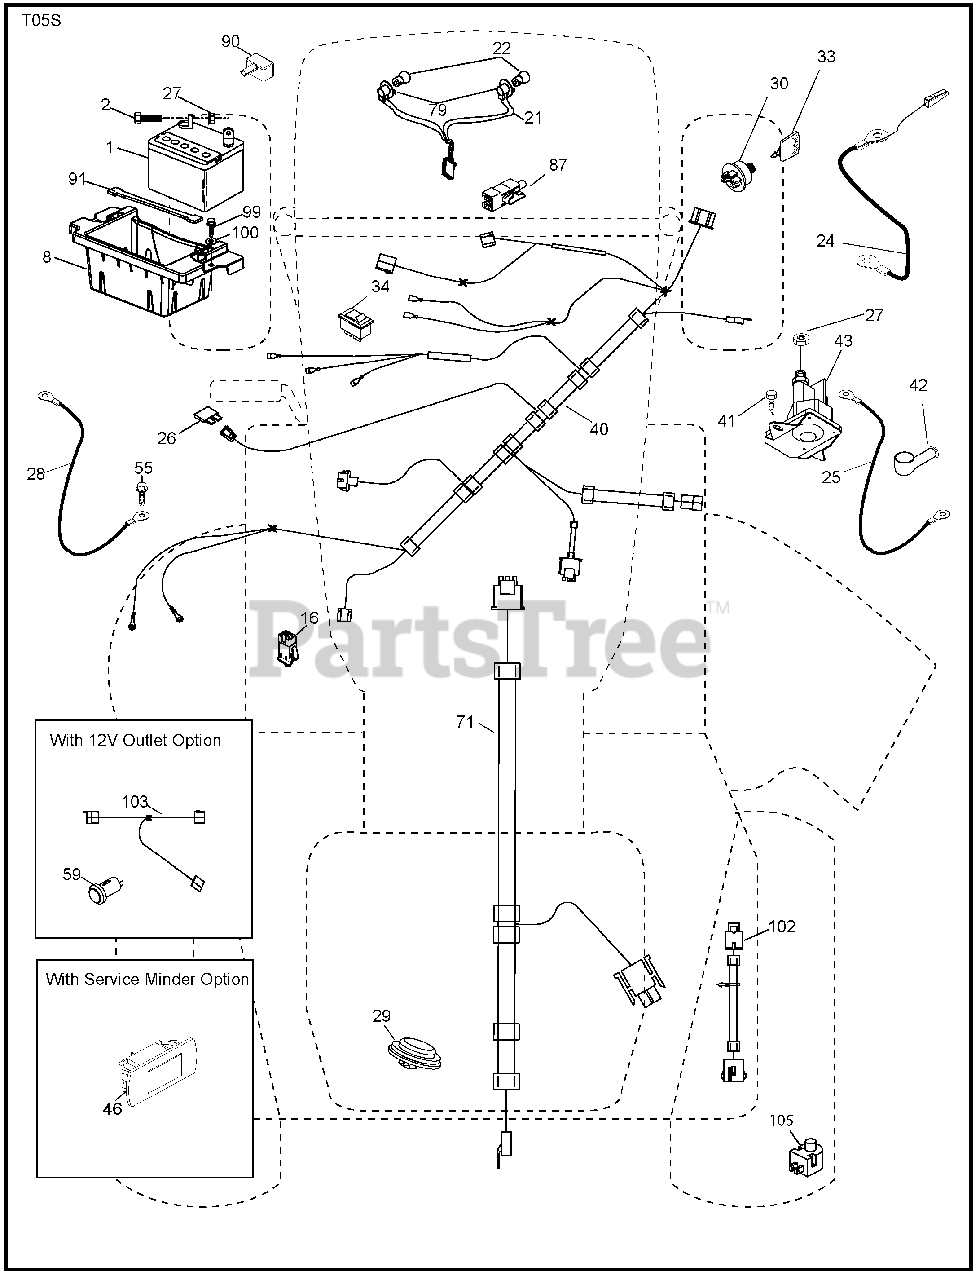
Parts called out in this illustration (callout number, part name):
1	Battery
2	Bolt Hex Head 1/4-20 x 3/4
8	Box Battery
16	Switch Interlock Push-In
21	Harness Socket Light w/4152J
22	Bulb Light
24	Cable Battery
25	Cable Starter
26	Fuse
27	Nut Keps Hex 1/4-20 unc
28	Cable, Ground
29	Switch, Seat
30	Switch, Ignition
33	Key/Chain
34	Switch Light/Reset
40	Harness Ignition Dash
41	Screw Thd Cut 1/4-20 x 1/2
42	Cover, Terminal
43	Solenoid
46	Gauge SRVCMNDR HRMTR
55	Screw Thdrol 5/16-18 x 3/4 TYTT
71	Harness Ignition
79	Socket Asm Bulb Twistlock
87	Switch Interlock Clutch Cable
90	Cover Terminal Battery
91	Strap Battery
99	Screw 1/4-20 x 3/4
100	Washer 9/32 x 7/8 x 16
102	Harness Pigtail
105	Switch Reverse
